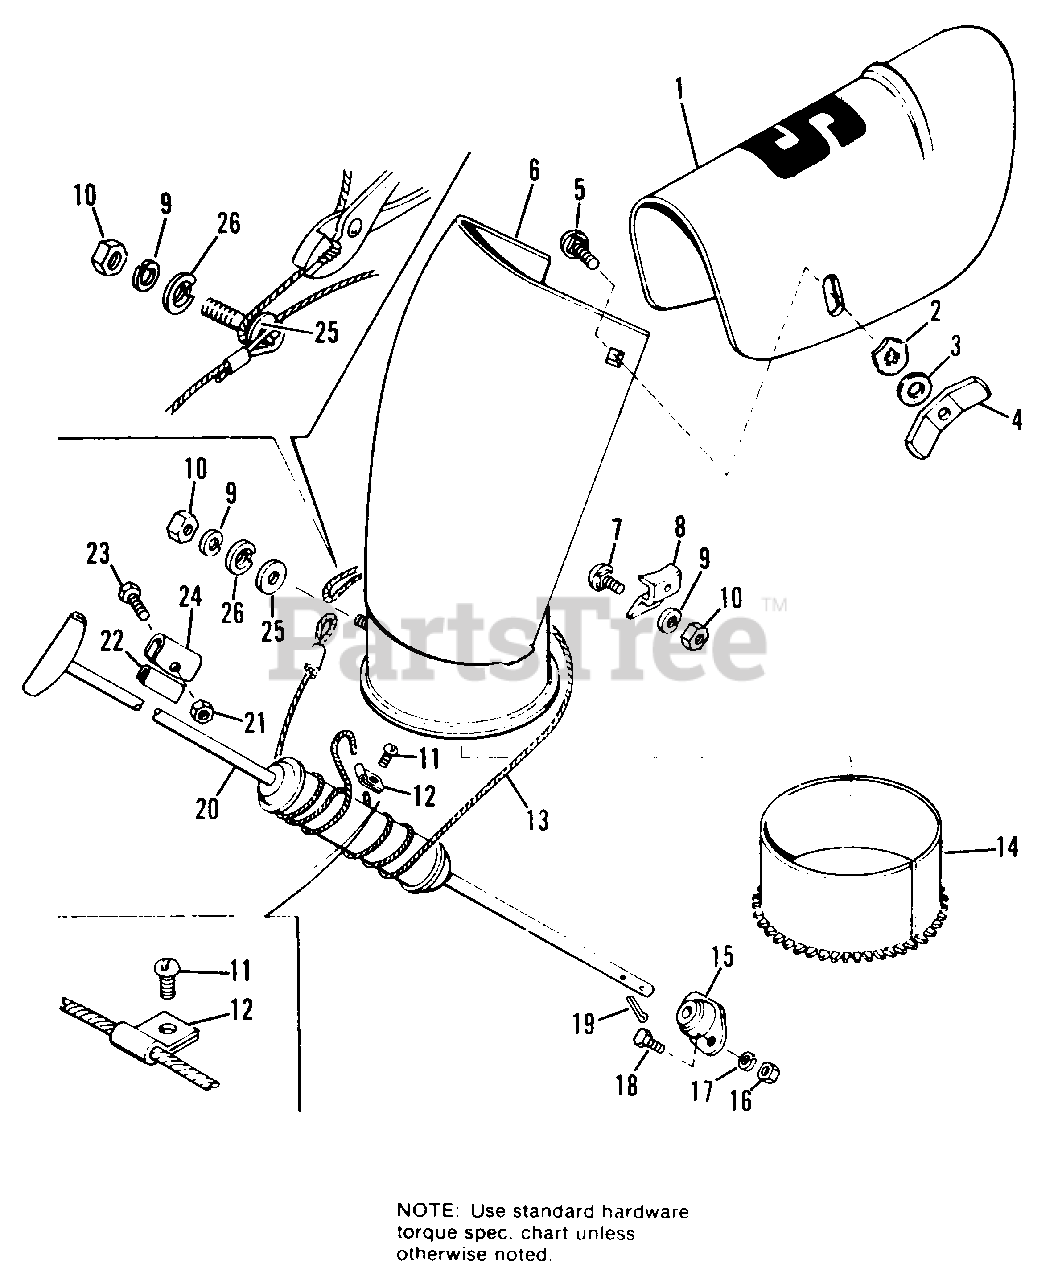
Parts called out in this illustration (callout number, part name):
1	EXTENSION, Spout
2	LOCKWASHER, Pyramdial Type, 3/8
3	WASHER, Plain, 3/8
4	NUT, Wing, 5/16-18
5	BOLT, Carriage, 5/16-18 x 3/4
6	SPOUT ASSY.
7	BOLT, Carriage, 5/16-18 x 3/4
8	PLATE, Hold Down
9	LOCKWASHER, 5/16
10	NUT, Hex, Full, 5/16-18
11	SCREW, Hex, Taptite, 1/4-20 x 3/8
13	CABLE ASSY.
16	NUT, Hex, Full, 1/4-20
17	LOCKWASHER, 1/4
18	CAPSCREW, Hex Hd., 1/4-20 x 5/8
19	PIN, Cotter, 1/8 x 3/4
20	TUBE ASSY., Spout Control
21	LOCKNUT, Hex, 5/16-18
23	CAPSCREW, Hex Hd., 5/16-18 x 1-1/4
25	WASHER, Plain, 1/4
26	CUP, Washer
